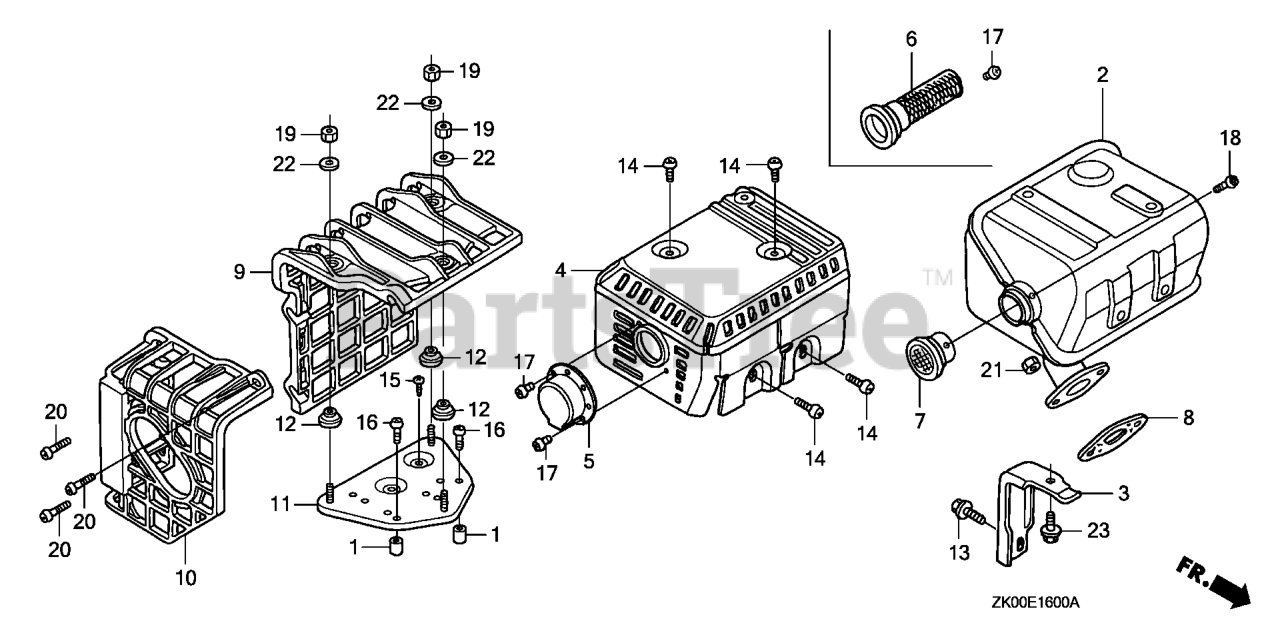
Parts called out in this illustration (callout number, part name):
3	STAY, MUFFLER
4	PROTECTOR, MUFFLER (SILENT)
6	ARRESTER, SPARK
7	NETTING, WIRE FLANGE
8	GASKET, MUFFLER
13	BOLT, FLANGE (6X13)
14	SCREW, TAPPING (5X8)
17	SCREW, TAPPING (4X6) (TO INSTALL OPTIONAL SPARK ARRESTER)
18	SCREW, TAPPING (4X6)
21	NUT, HEX. (8MM)
23	BOLT, FLANGE (6X12) Use up to Engine SN 1543277.
